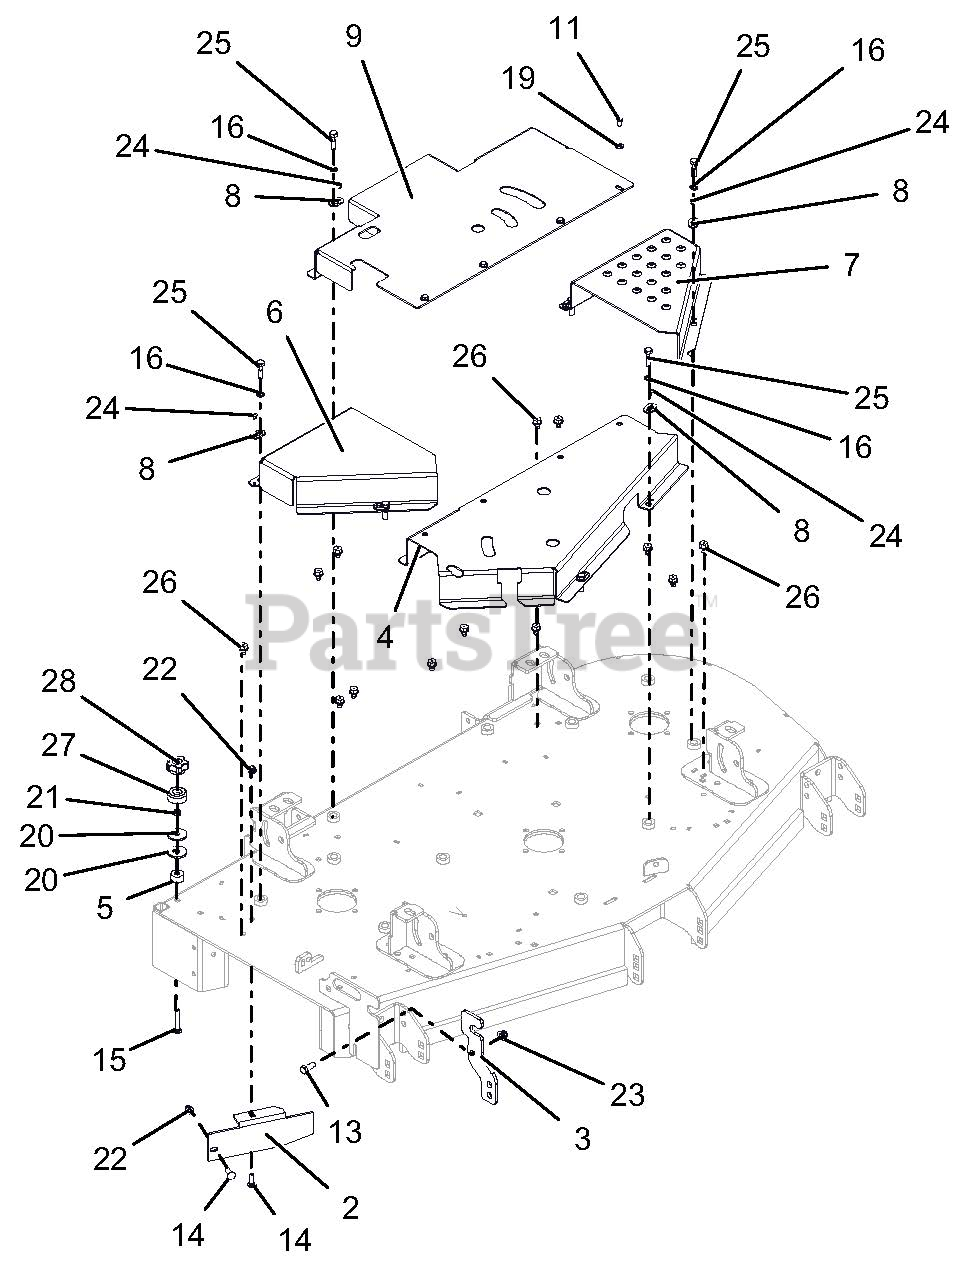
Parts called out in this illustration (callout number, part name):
2	BAFFLE, 52" DISCHARGE
3	CHUTE STORAGE BRACKET
4	WLDMT, FRONT BELT SHIELD
5	SPACER .390X1.000X.562
6	GUARD, RH PT200 CE BELT
7	GUARD, LH PT200 CE BELT
8	KEEPER, BOLT
9	SHIELD, BELT REAR
11	BLT-HEX .25-20X.50 GR5 YWZC
13	BLT-HEX .38-16X1.00 GR5 YWZC
14	BLT-RDHDSQSHNK .31-18X1.00 G5 Y
15	BLT-RDHDSQNK .31-18X2.0 FTH G5 Y
16	LOCK, WSHR-EXT 0.391 X 0.628 X 0.036 YWZC
19	WSHR-FL-STL.281X.62X.065 YWZC
20	WSHR-FL-STL .380X1.50X.125 YWZC
21	NUT-LK-CTR .31-18 YWZC
22	NUT-LK-NYL-FLG .31-18 YWZC
23	NUT-LK-NYL-FLG .38-16 YWZC
24	RVT-POP .187x.250 (#64) YWZC
25	BLT, HEX 0.38-16 X 1.25 GR5 CAPTIVE
26	SCR-TAP .38-16X.50 HWH TR YWZ
27	BUMPER, RECESSED 1.50 X .63 W/.31 HOLE
28	KNOB, CLAMPING
